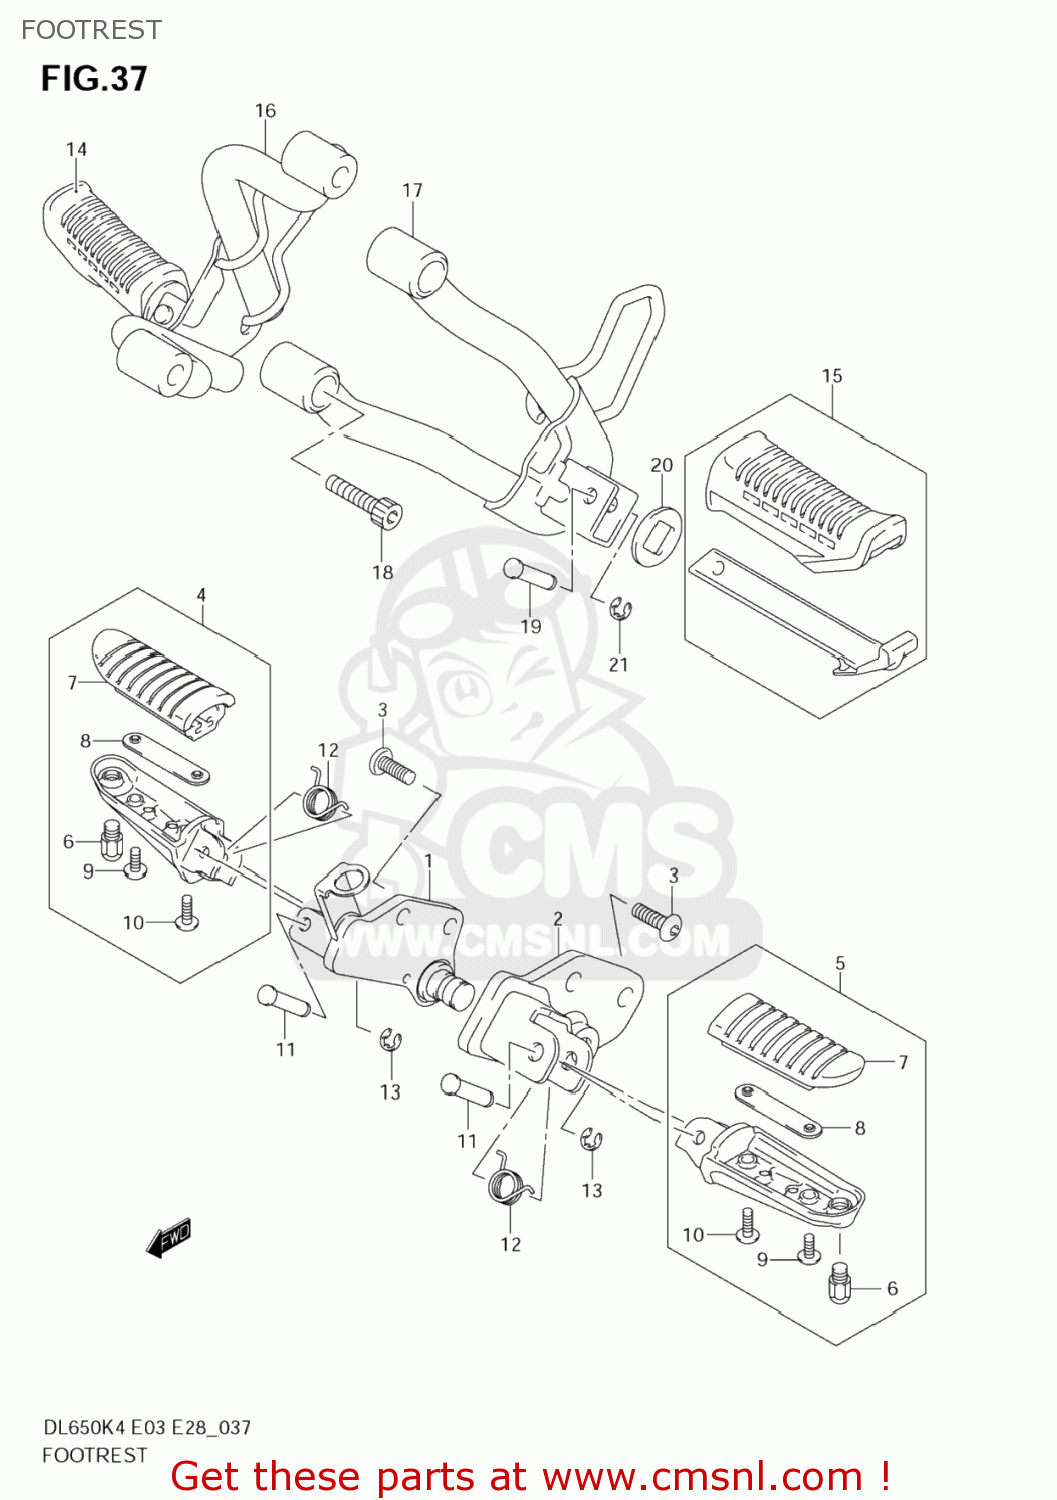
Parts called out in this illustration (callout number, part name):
1	BRACKET COMP,F
2	BRACKET,FR FOO
3	BOLT(8X23)
4	FOOTREST ASSY,PILLION,R
5	FOOTREST ASSY,PILLION,L
6	BOLT,BANK SENSOR
7	RUBBER,FOOTREST
8	PLATE,FR FOOTREST RUBBER
9	SCREW
10	SCREW 5X20
11	PIN(8X33.2)
12	SPRING
13	E.RING
14	FOOTREST ASSY,PILLION,R
15	FOOTREST ASSY,PILLION,L
16	BRACKET
17	BRACKET,PILLION FOOTREST,L(BLA
18	BOLT(8X40)
19	PIN
20	WASHER,FOOTREST RUBBER
21	E-RING
